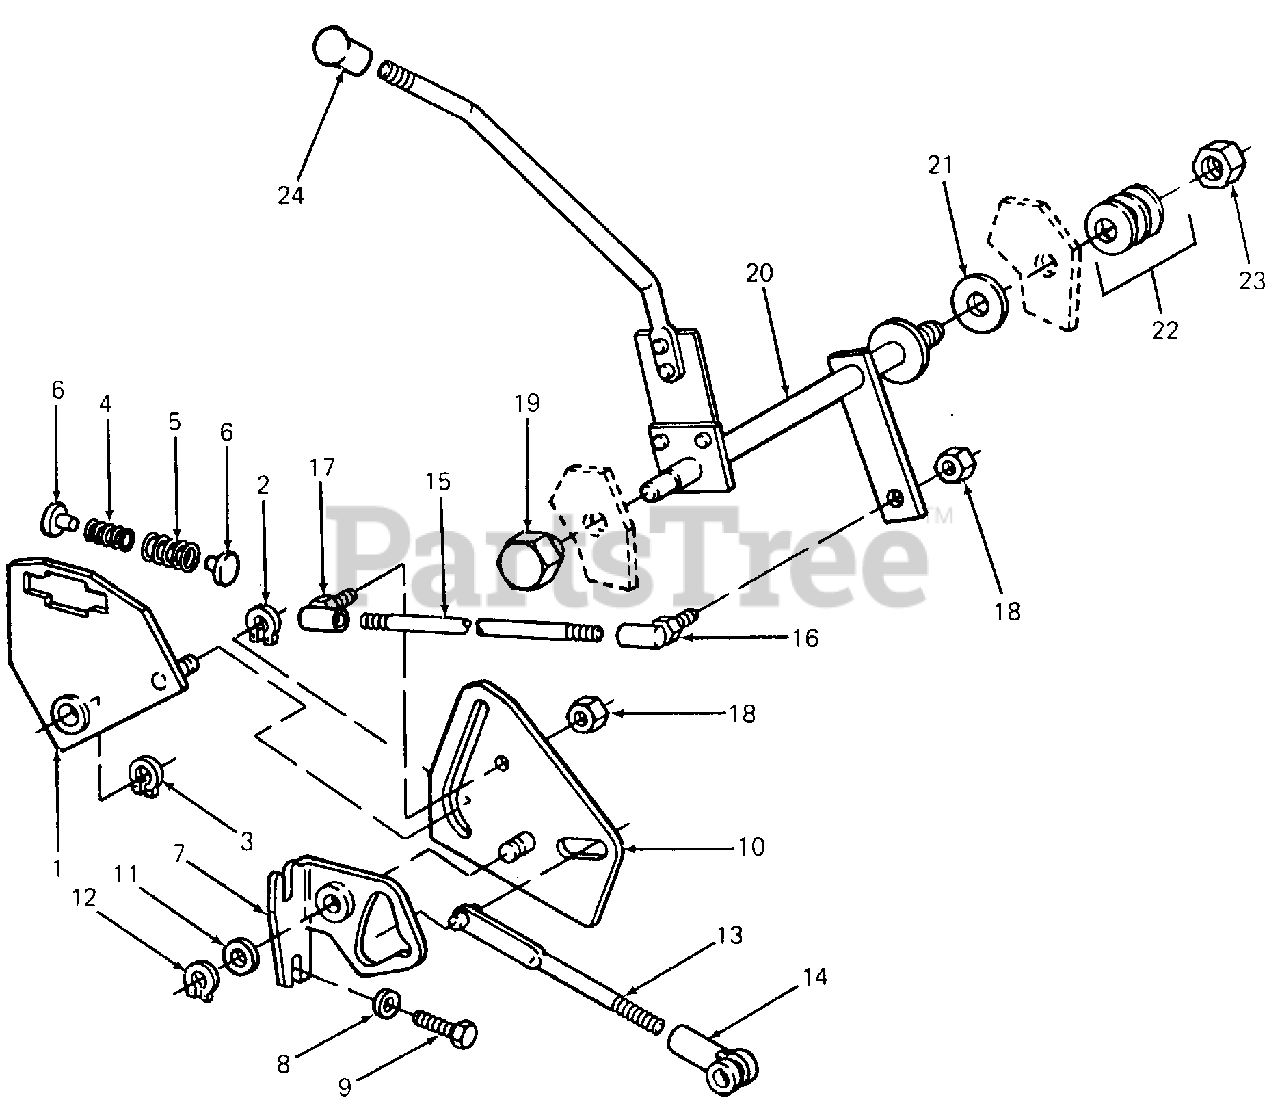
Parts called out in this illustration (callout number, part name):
1	Plate Assy, Damper Spring
2	Ring, Snap, .375
3	Ring, Snap, .625
4	Spring, Compression
5	Spring, Compression
6	Pin, Spring Guide
7	Bracket, Cam Pivot
8	Washer, Flat, .385 X .87 X .06 Thk HDN
9	Screw, Hex Cap, 3/8-16 X 1.5 Lg GR5
10	Cam, Control
11	Washer, Flat, .510 X 1.0 X .06 Thk
12	Ring, Snap, .500
13	Rod, Control
14	Clevis, Adjustment
15	Rod, Connecting
16	Ball Joint, 5/16-24
17	Ball Joint, 5/16-24 LH Trd
18	Nut, Hex Patch Lock, 5/16-24
19	Screw, Rockshaft Bearing, 3/4-16 X .75 Lg
20	Shaft Assy, Cross
21	Disc, Friction
22	Washer, Bell
23	Nut, Hex Top Lock, 1/2-20
24	Knob, Control
